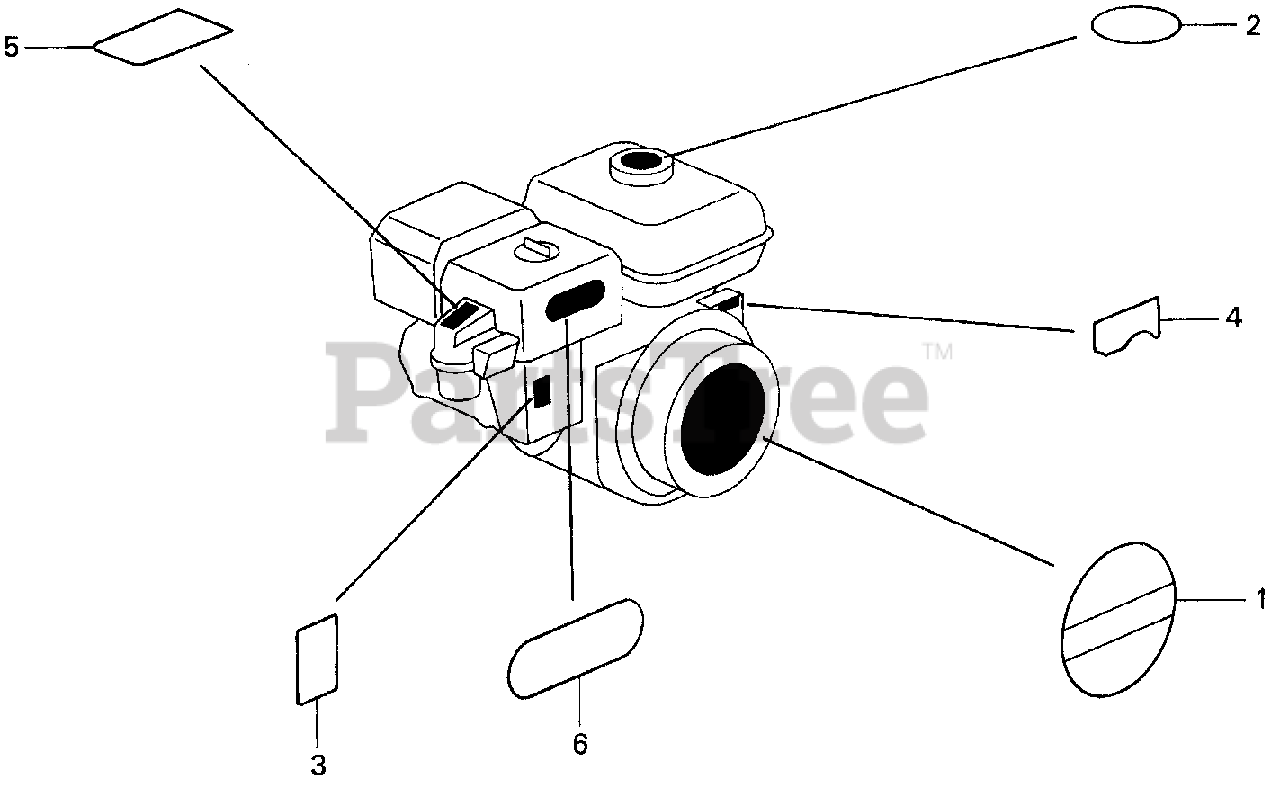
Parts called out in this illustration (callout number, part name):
1	EMBLEM (EXTERNAL-ALERT)
2	MARK, CAUTION (EXTERNAL)
3	MARK, CHOKE
4	MARK, OIL ALERT (EXTERNAL)
